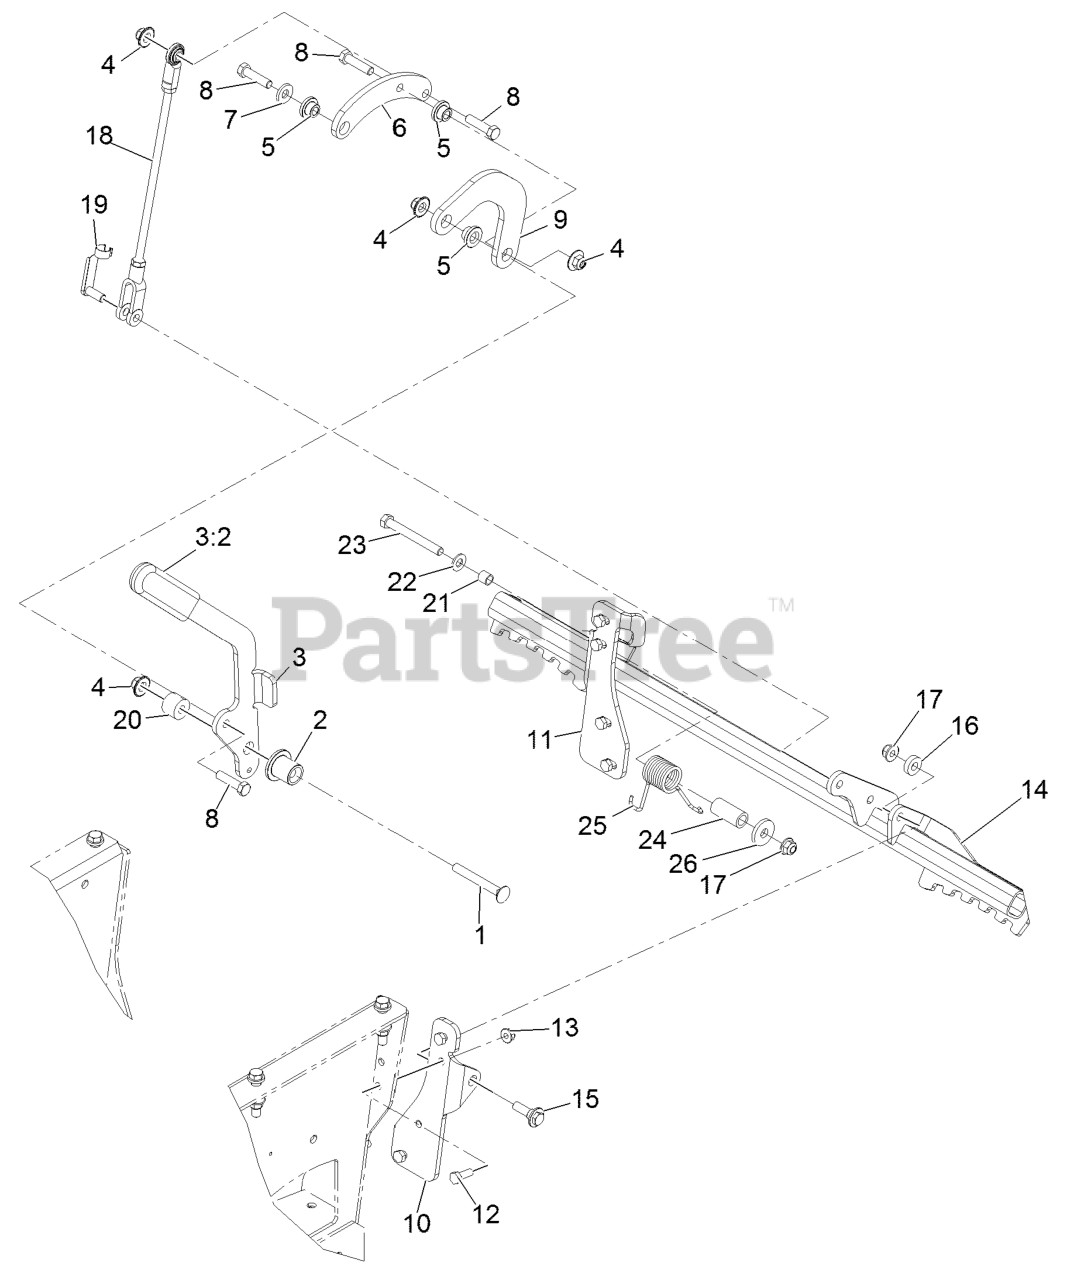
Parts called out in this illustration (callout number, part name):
1	SCREW-CARR
2	BUSHING-HANDLE
3	HANDLE-W/GRIP ASM
3:2	GRIP-LEVER
4	Nut-Nyloc 3/8-16 Flg
5	BUSHING-FLANGED
6	ARM-BRAKE BELLCRANK
7	WASHER-BELLEVILLE
8	SCREW-HH
9	LINK-BRAKE HANDLE
10	BRACKET-BRAKE MOUNT, LH
11	BRACKET-BRAKE MOUNT, RH
12	SCREW-HH
13	NUT-HF, NI
14	BAR-BRAKE
15	SCREW-SHOULDER, HWH
16	SPACER
17	NUT-HF, NI
18	ASM-BRAKE LINKAGE
19	PIN-SPRING, CLEVIS
22	WASHER-FLAT
23	SCREW-HH
25	SPRING-TORSION
